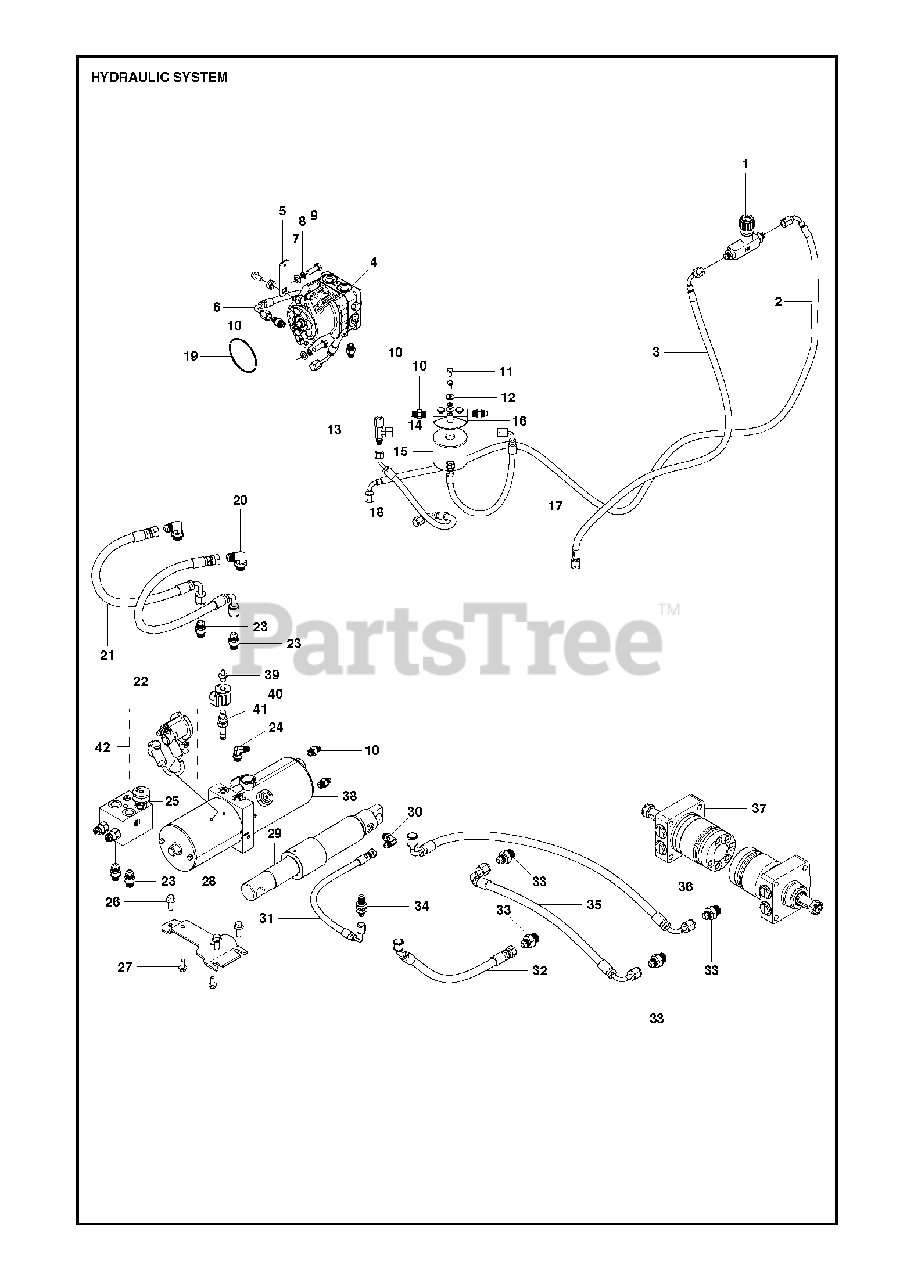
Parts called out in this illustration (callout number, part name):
7	WASHER
17	HYDRAULIC HOSEFilter-Pump
18	HYDRAULIC HOSEFilter-Reservoir
21	HYDRAULIC HOSEPump A - Block A2
22	HYDRAULIC HOSEPump A - Block B2
31	HYDRAULIC HOSELift Cylinder - Block
32	HYDRAULIC HOSEHydraulic Motor - Block
35	HYDRAULIC HOSEHydraulic Motor
36	HYDRAULIC HOSEHydraulic Motor - Block
